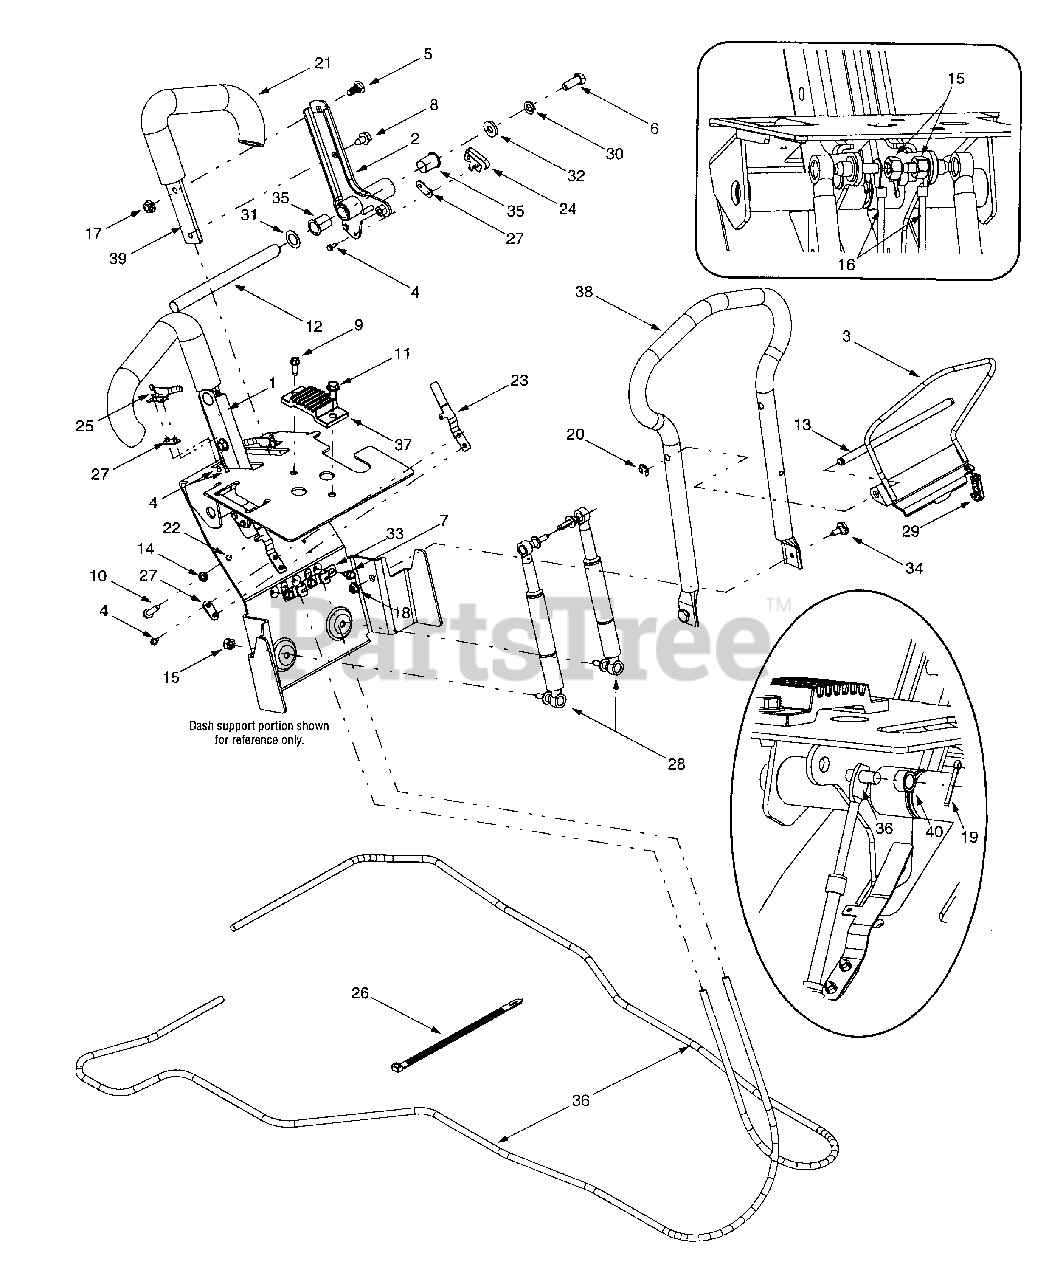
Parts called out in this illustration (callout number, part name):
4	Self-tapping Screw, #8-18 x .5
5	Carriage Screw, 5/16-18 x .75
6	Hex Cap Screw, 3/8-16 x 1.0
7	Self-tapping Screw, 1/4-20 x.5
8	Self-tapping Screw, 16-18 x .625
9	Self-tapping Screw, 1/4-20 x .75
10	Self-tapping Screw, 1/4-20 x 1.0
11	Self-tapping Screw, 5/16-18 x .75
12	Control Shaft
13	Rod, .375 x 8.0
14	Jam Nut, 1 /4-20
15	Center Lock Hex Nut, M8
16	Ground Jumper Wire Assembly
17	Flange Lock Nut, 5/16-18
18	Hex Flange Lock Nut, 114-20
19	Cotter Pin, 3/32 x .75
20	E-Ring, .375
21	Foam Grip
22	Dipped Cap, .187
23	Spring Switch
24	Short Spring Switch
25	Lever Spring Switch
26	Cable Tie
27	Insulator Nut Plate
28	Damper Cylinder
29	Extension Spring, .50 x 2.54
30	Lock Washer, 3/8
31	Flat Washer, .63 x 1.0 x .020
32	Flat Washer, .406 x .875 x .105
33	Clamp Cable Bracket
34	Shoulder Screw, .375 x .181
35	Flange Bearing, .630 x .693
36	Control Cable, 77.5
37	Index Plate
